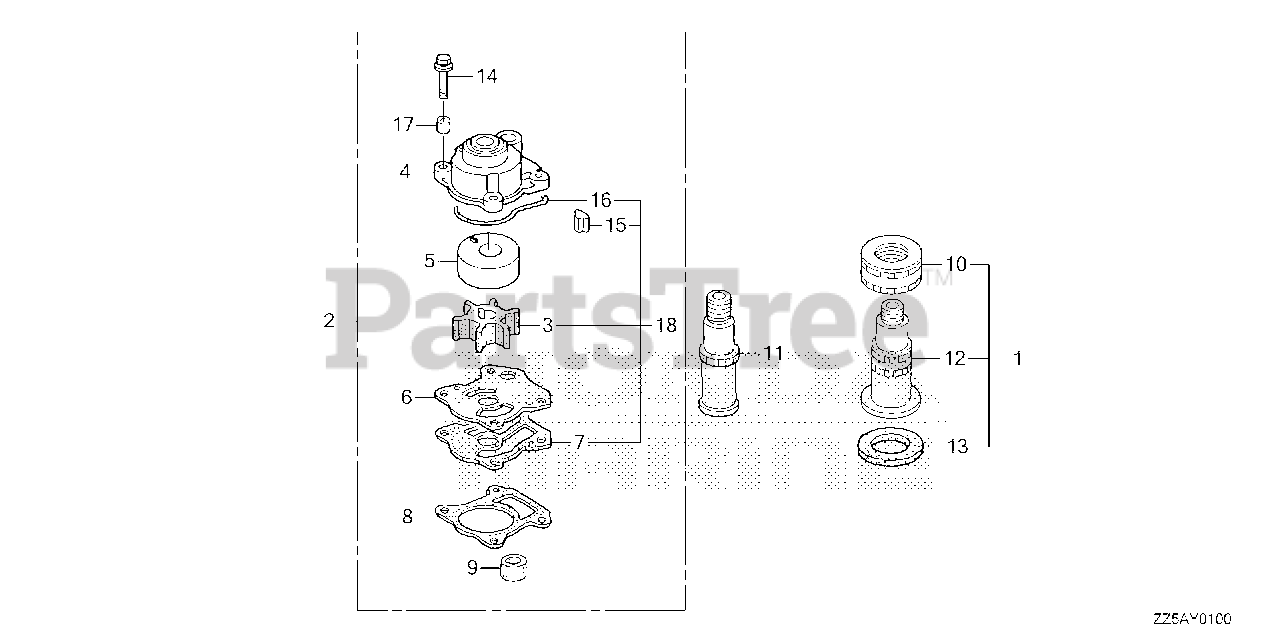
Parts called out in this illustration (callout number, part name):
2	PUMP KIT, IMPELLER (INCLUDES IMPELLER HOUSING)
3	IMPELLER, PUMP
4	HOUSING, IMPELLER
5	LINER, PUMP
6	COVER, IMPELLER
7	GASKET B, IMPELLER
8	GASKET, WATER PUMP
9	RING, WATER TUBE SEAL
11	JOINT, WATER HOSE
14	BOLT-WASHER (6X40)
15	KEY, WOODRUFF
16	O-RING, WATER PUMP
17	COLLAR, IMPELLER HOUSING
18	PUMP KIT, IMPELLER
